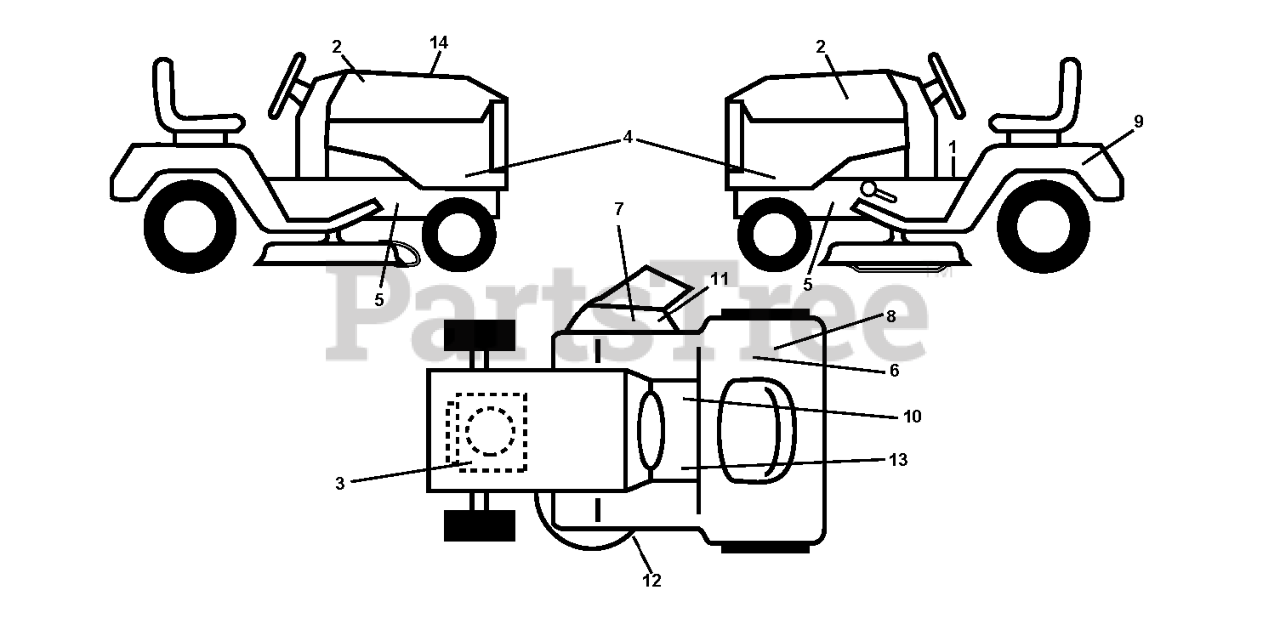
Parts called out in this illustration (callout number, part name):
1	LABEL
2	DECAL.HOOD.LOGO.ORANGE.HUSQVAR
3	DECAL
6	DECAL 80 DBA
7	DECAL.INTERNATIONL.CUTFINGER
8	DECAL
9	DECAL BTRY SYMBOLS
10	DECAL PARK BRAKE
11	DECAL, DEFLECT WARNING
12	DECAL.V-BELT.SCHEMATIC.36/38/9
13	DECAL
